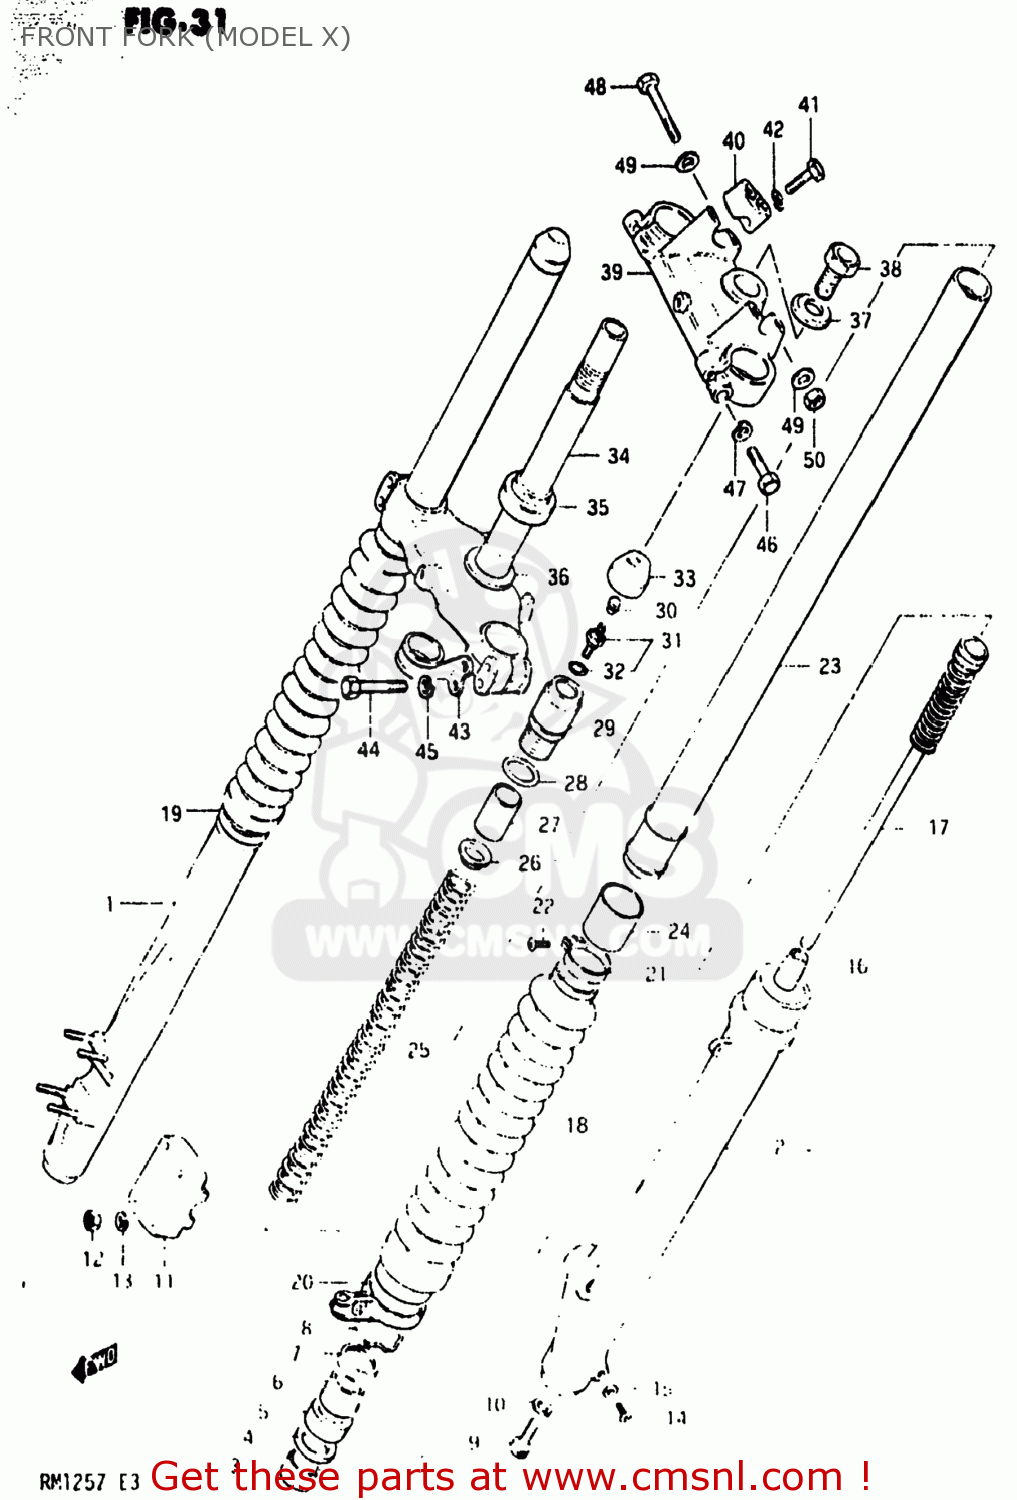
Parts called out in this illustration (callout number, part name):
1	TUBE,OUTER,RIGHT
2	TUBE,OUTER,LEFT
3	METAL,SLIDE
4	WASHER(40X50X2.3)
5	SEAL,OIL
6	SEAL,DUST
7	CASE,DUST SEAL
8	RING,STOPPER
9	BOLT,CYLINDER
10	GASKET,CYLINDER (NAS)
11	HOLDER,AXLE
12	NUT
13	LOCK WASHER
14	SCREW
15	GASKET,DRAIN,PLUG (NAS)
16	PIECE,OIL LOCK
17	CYLINDER,FRONT FORK
18	BOOT
19	BAND,FRONT FORK COVER BOOT
20	BAND,FRONT FORK COVER BOOT
21	BAND,BOOT
22	SCREW 4X10
23	TUBE,FORK,INNER
24	PISTON
25	SPRING,FRONT FORK
26	GUIDE
27	SPACER,FRONT FORK SPRING
28	O RING
29	CAP,FORK INNER TUBE
30	CAP,VALVE AIR
31	VALVE
32	O RING
33	CAP
34	STEM,STEERING
35	BEARING
36	WASHER,THRUST
37	WASHER
38	BOLT
39	HEAD,STEERING STEM
40	HOLDER,HANDLEBAR
41	BOLT
42	LOCK WASHER
43	CLIP,CABLE
44	BOLT 8X45
45	LOCK WASHER
46	BOLT
47	LOCK WASHER
48	BOLT 8X50
49	WASHER
50	NUT
